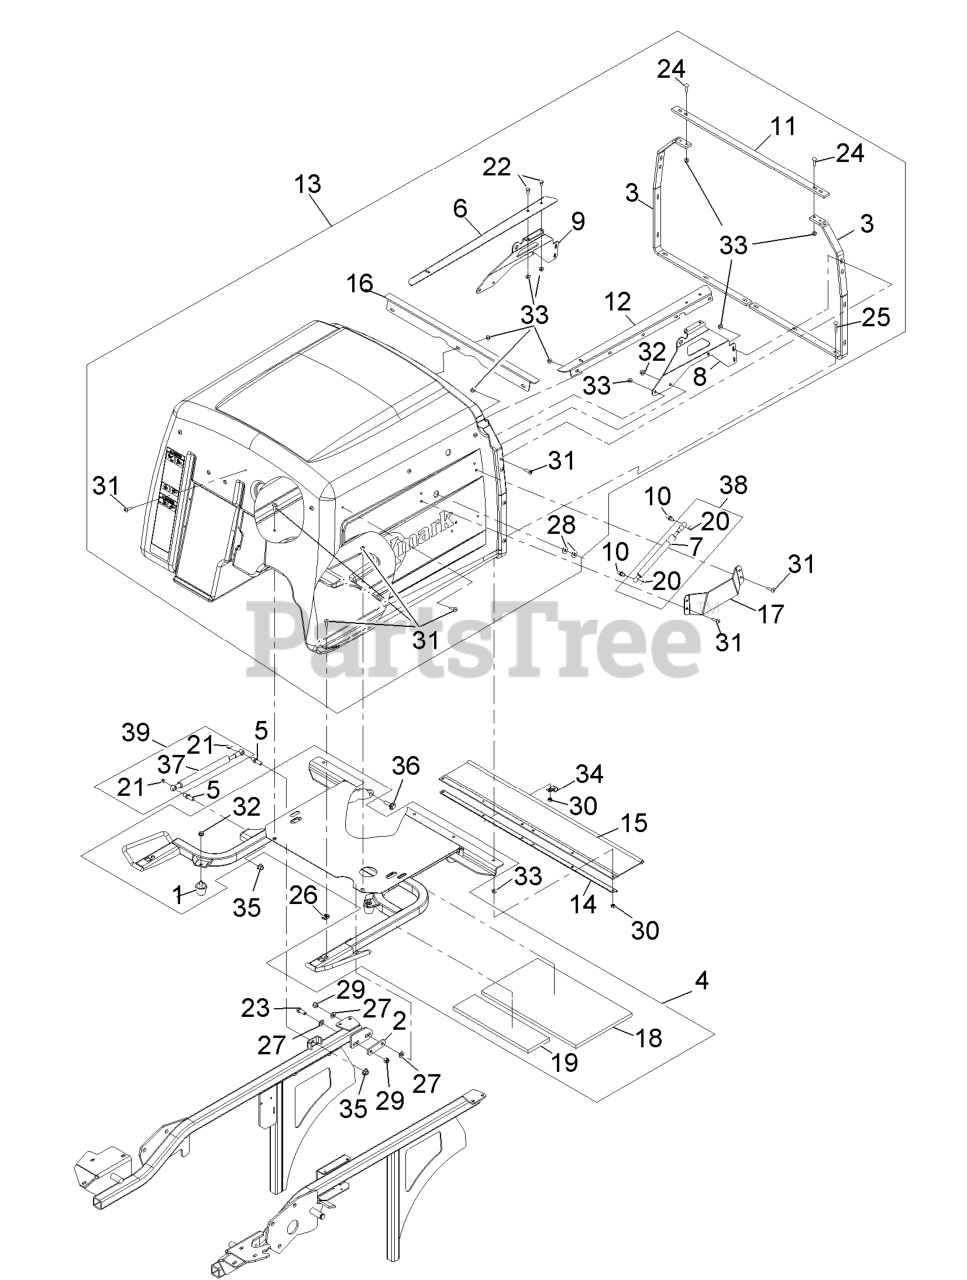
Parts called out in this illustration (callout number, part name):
1	BUMPER-RUBBER
2	ARM-LIFT, DECK
3	REINFORCEMENT-HOPPER
4	HOPPER FRAME ASM
5	STUD-BALL
6	ANGLE-SCREEN TRACK, RH
7	SHOCK-GAS TENSION
8	BRACE-DOOR PIVOT, LH
9	BRACE-DOOR PIVOT, RH
10	STUD-BALL
11	BRACKET-FRAME CONNECT
12	ANGLE-SCREEN TRACK, LH
13	ASM,HOPPER
14	CHANNEL-FRAME, HOPPER
15	DEFLECTOR-GRASS
16	CHANNEL-SCREEN, FRONT
17	PLATE-GUARD
18	INSULATION-FOAM PAD, REAR
19	INSULATION-FOAM PAD, FRON
20	CLIP-RETAINER
21	CLIP-RETAINER
22	SCREW-HH
23	SCREW-HH
24	SCREW-CARR
25	SCREW-CARR
26	Nut-Retainer-Panel 1/4-20
27	WASHER-FLAT
28	WASHER-FLAT
29	NUT-LOCK, NI
30	NUT-LOCK, NI
31	SCREW-TTH
34	CLIP-LOOM
36	SCREW-SHOULDER, HWH
37	SHOCK-COMPRESSION, GAS
38	DAMPER KIT
39	DAMPER KIT
